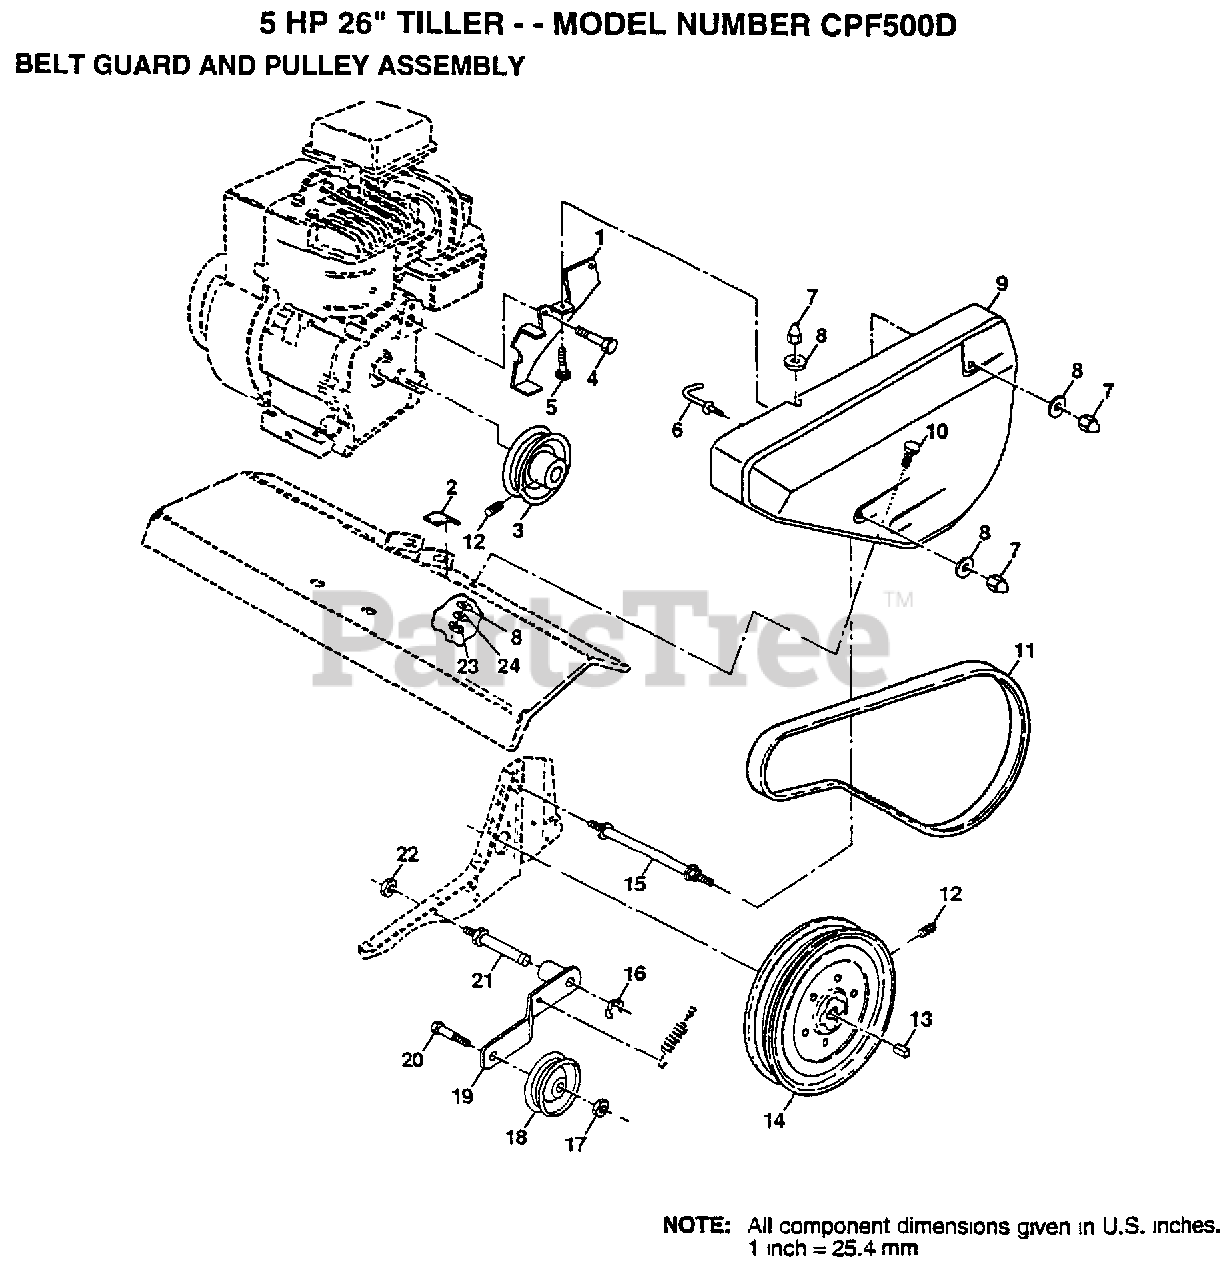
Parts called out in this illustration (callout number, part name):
2	PAD IDLER TI
3	ENGINE PULLEY
5	BOLT
7	NUT-CAP TI
8	WASHER
10	BOLT T
11	V BELT STD
12	SET SCREW
13	KEY T
14	TRANS SHEAVE RT
15	BOLT TI
16	KLIP RING TI
17	NUT
19	IDLER ARM TI
21	SHAFT IDLER TI
22	JAM NUT TI
24	LOCKWASHER
